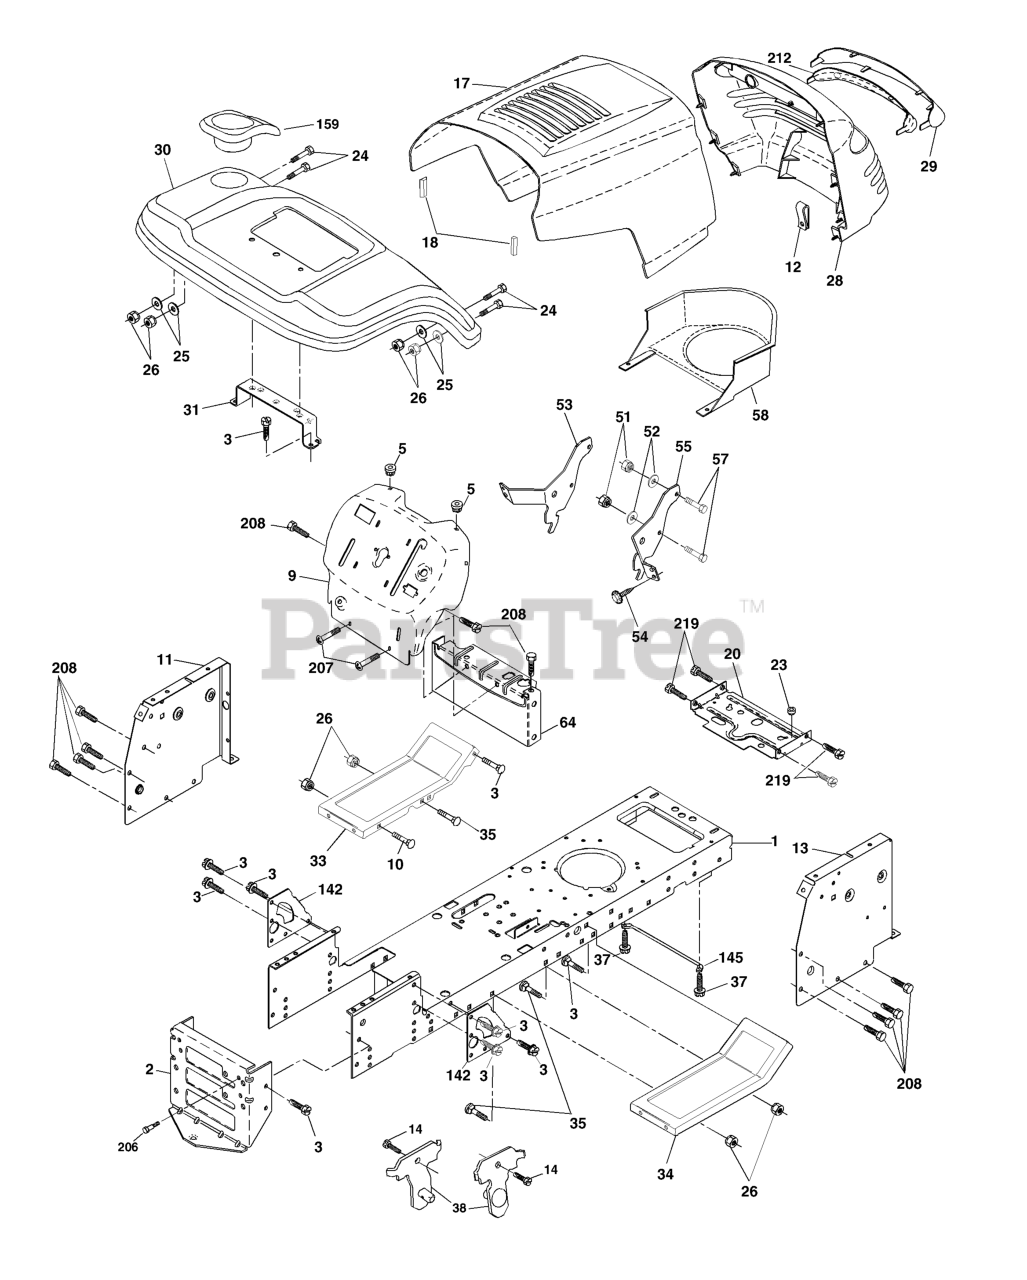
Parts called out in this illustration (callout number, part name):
1	CHASSIS STAMPING
2	DRAWBAR, 12GA
3	SCREW 3/8-16X3/4
5	BUMPER.RUBBER.HOOD
9	DASH(SUBS)
10	BOLT D
11	PANEL.DASH.LH.LTX
13	PANEL DASH RH
14	SCREW LT
17	HOOD ASM.
18	BUMPER HOOD T
20	PLATE MTG.BATTERY/FUEL TANK
23	BUSHING.SNAP.NYL.BLK.
24	BOLT
25	WASHER
26	NUT
28	GRILLE/LENS ASM
29	LENS
30	FENDER, YTH1746
31	BRACKET FENDER
33	FOOTREST PNT LH
34	FOOTREST PNT RH
35	BOLT
37	Screw Thdrol 6/16-18 x 1/2 TYT
38	BRACKET.ASM.PIVOT.MOWER.REAR
51	LOCKNUT.NYLOC.1/4-20
52	WASHER
53	BRACKET.GRILLE.LH
54	SCREW.HEX.WS.HD.8-18 X 7/8
57	BOLT
58	AIR DUCT P/L/LT
64	DASH LOWER
142	PLATE REINFORCEMENT
145	ROD PIVOT CHASSIS/HOOD
159	CUPHOLDER
206	SHOULDER BOLT 5/16-18TT
207	SCREW, 5/16-18 X 1/2
208	SCREW 3/8-16X1/2
212	REPL BY 532 1745-03
219	SCREW
